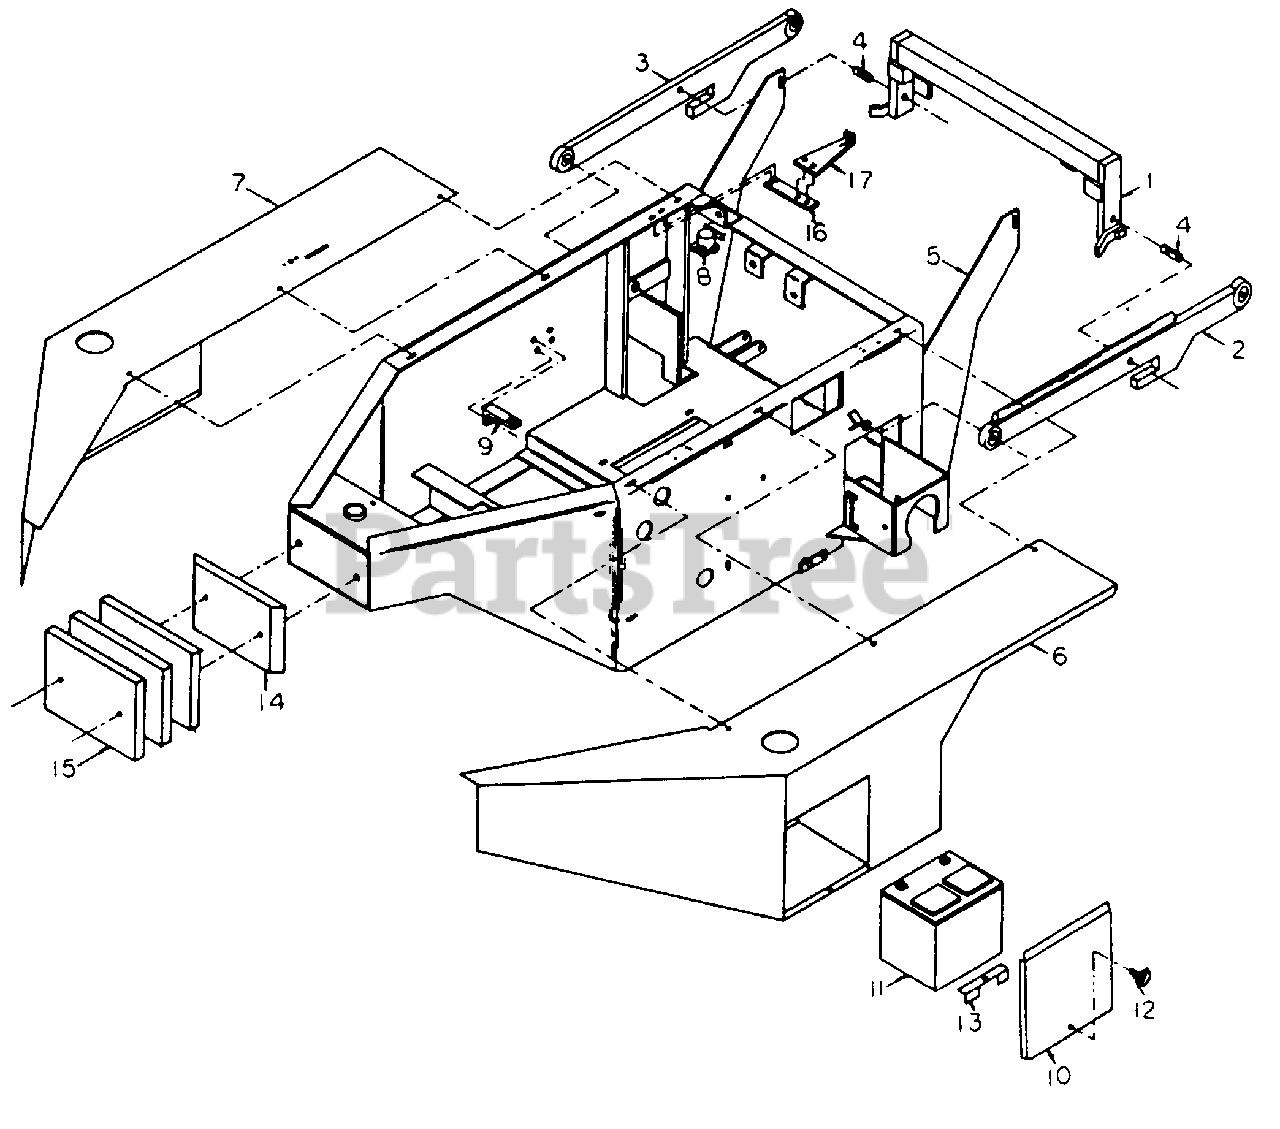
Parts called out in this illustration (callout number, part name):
2	Deck Llft Arm, RH
3	Deck Llft Arm, LH
4	Llft Bar Bushlng
5	Base
6	Fender, RH
9	Ihrottle Bracket
10	Battery Box Lid
11	Battery
13	Battery Hold Down
14	Tail Cap
16	Mount, Fuel Shutoff Valve
17	Retalner, Fuel Shutoff Valve
